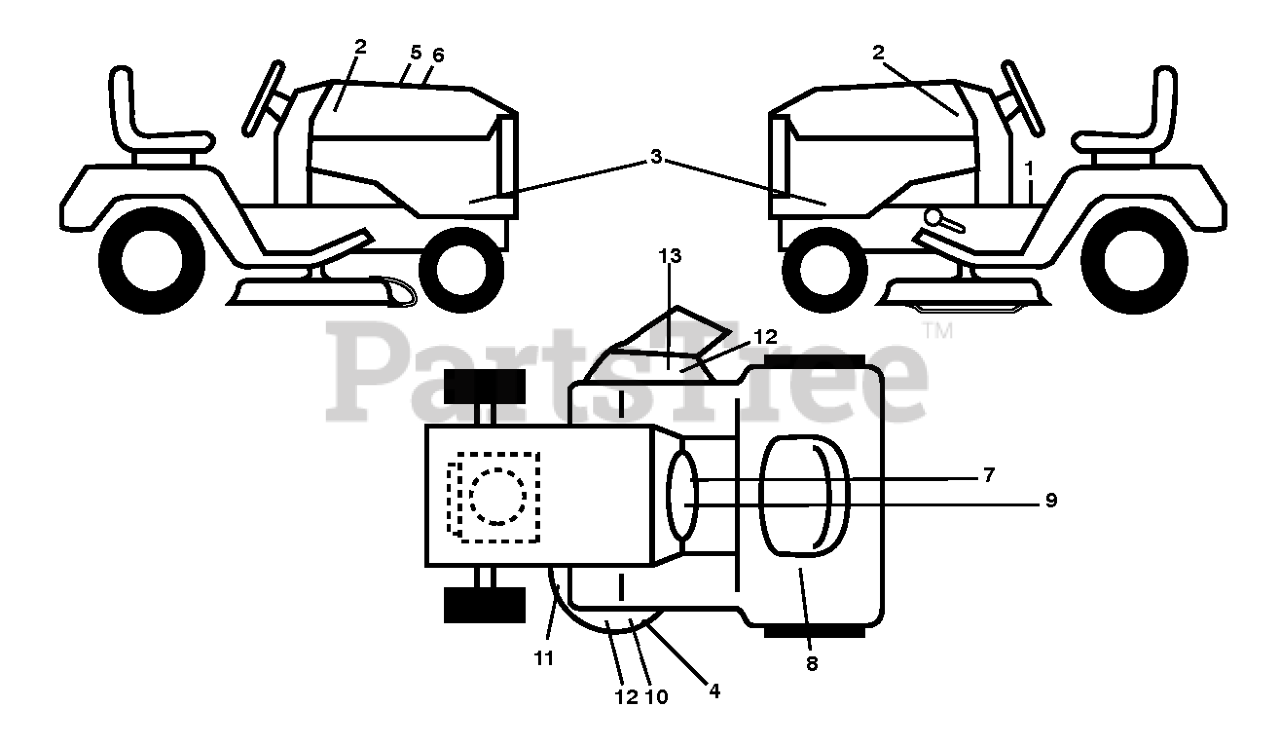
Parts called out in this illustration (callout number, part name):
1	DECAL.FENDER.WARNING.ENGLISH
2	DECAL.BADGE.170MM.TEXTLOGO.
3	DECAL.SDPL.HUSQGT.YT48DXLS.SET
4	DECAL DECK DECAL DECAL.DECK.WA
5	DECAL.WARNING.CUST.RESP.E85.
6	DECAL.RPL.KAW.FR.TLB.48F.K46L
7	DECALS.WARN.CA.SPKARREST/PROP
8	DECAL.RESERVEFUELSELCTR.ENG
9	DECAL CARB EMISS.CA.HUSQ
10	DECAL DECK DECAL DECAL.48DECK.
11	DECAL.MOWER.SCH.48/54.PREM
12	DECAL.DECK.CLEARCUT.NOSTEP
13	DECAL.TRACT/ZTR.DECKWARN.HUSQ
